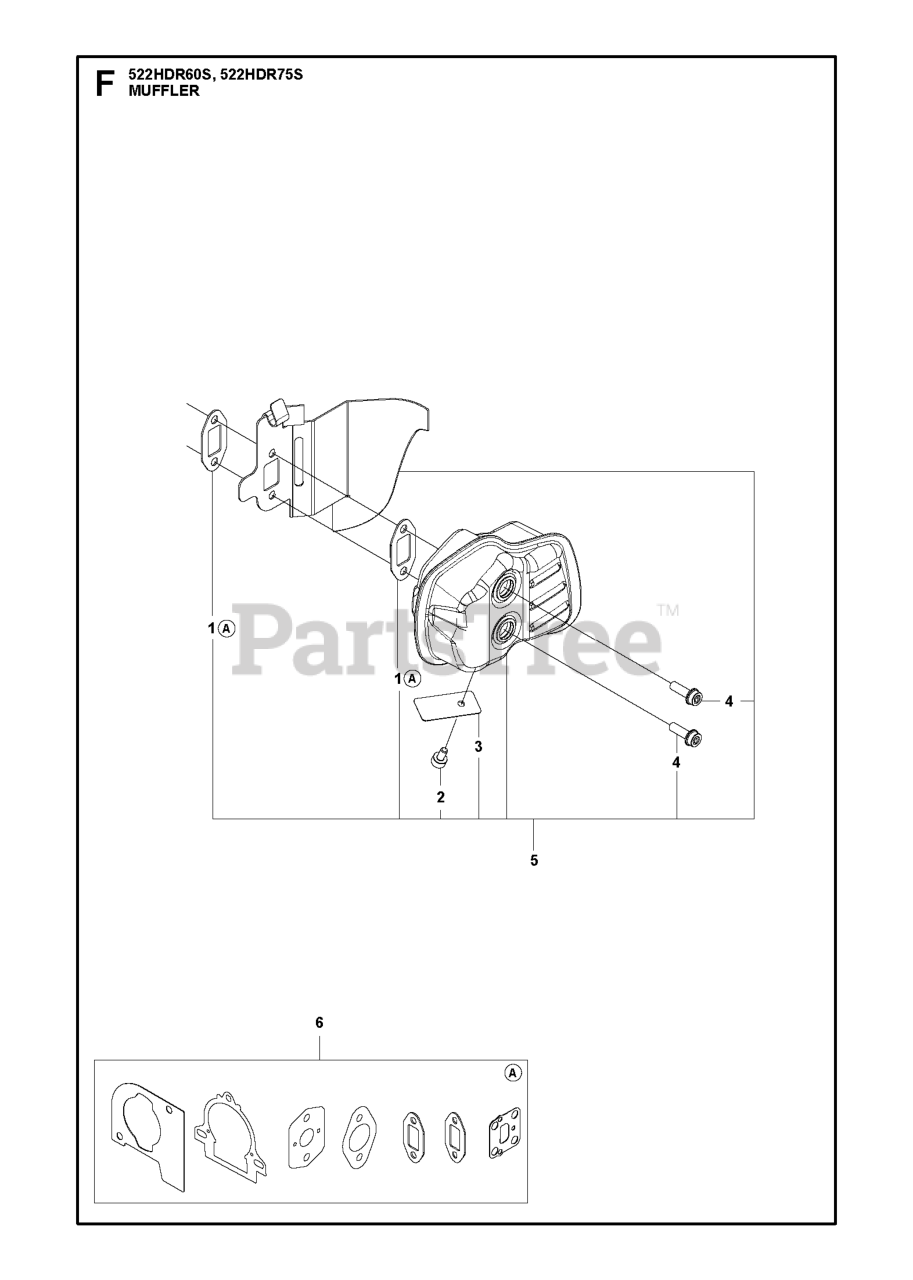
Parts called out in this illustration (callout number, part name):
1	GASKET MUFFLER
2	SCREW ITXSCM
3	SPARK ARRESTER
5	MUFFLER ASSY
6	GASKET KIT 522
